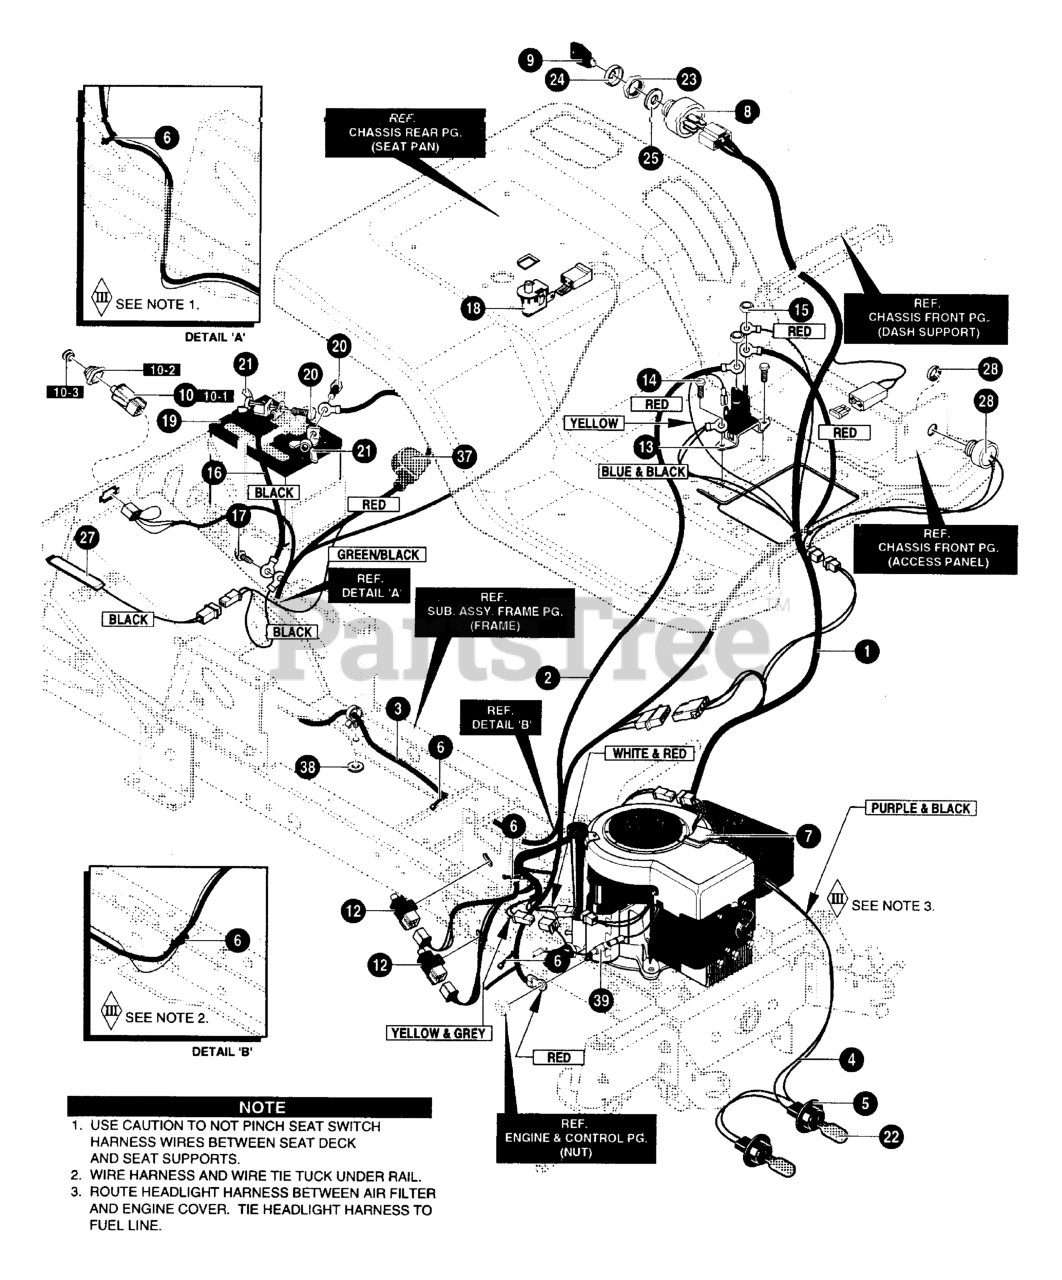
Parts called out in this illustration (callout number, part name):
1	WIRE HARNESS
2	WIRE, LEAD
3	REAR HARNESS
4	WIRE HARNESS FOR HEADLIGHTS
5	SOCKET, LAMP
6	TIE, CABLE BLACK NYLON 5.62L
7	WIRE CLIP, ADHESIVE
8	SWITCH, IGNITION
9	KEY, IGNITION
10	ASSY, SWITCH DOUBLE
10-1	SWITCH, DOUBLE
10-2	BOOT, SWITCH
10-3	CAP, SWITCH
12	SWITCH LIMIT
13	SOLENOID
14	SCREW, 1/4X.50
15	NUT, 1/4-20 HEXNYL
16	WIRE, GROUND
17	SCREW,1/4X.50
18	SWITCH, SEAT
19	BATTERY 12V 7 PLATE
20	BOLT,1/4-20X.63
21	NUT, WING 1/4-20
22	BULB, HEADLIGHT
23	NUT, 5/8-8 ACME
24	BOOT, IGNITION SWITCH
25	WASHER, REGINTLK
27	TAPE SWITCH
28	BUZZER, FOR BAG FULL
37	BATTERY BOOT
38	FLATWASHER, .250X.56X.0478
39	HARNESS ADAPTER
